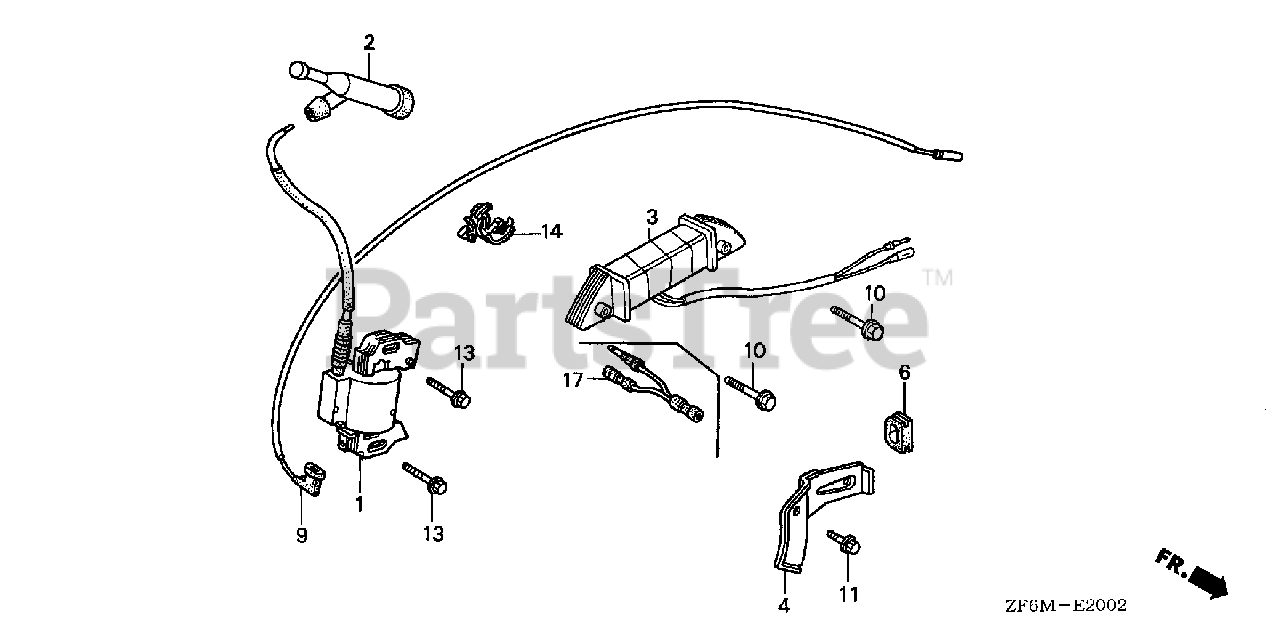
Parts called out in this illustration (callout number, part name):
1	COIL ASSY., IGNITION
2	CAP ASSY., NOISE SUPPRESSOR
3	COIL ASSY., LAMP (12V/25W)
4	CLAMP, WIRE
6	GROMMET, WIRE
9	WIRE, STOP SWITCH (470MM)
10	BOLT, FLANGE (6X40)
11	BOLT, FLANGE (6X12) (CT200)
13	BOLT, FLANGE (6X28)
14	CLIP, WIRE HARNESS
17	SUB-HARNESS
